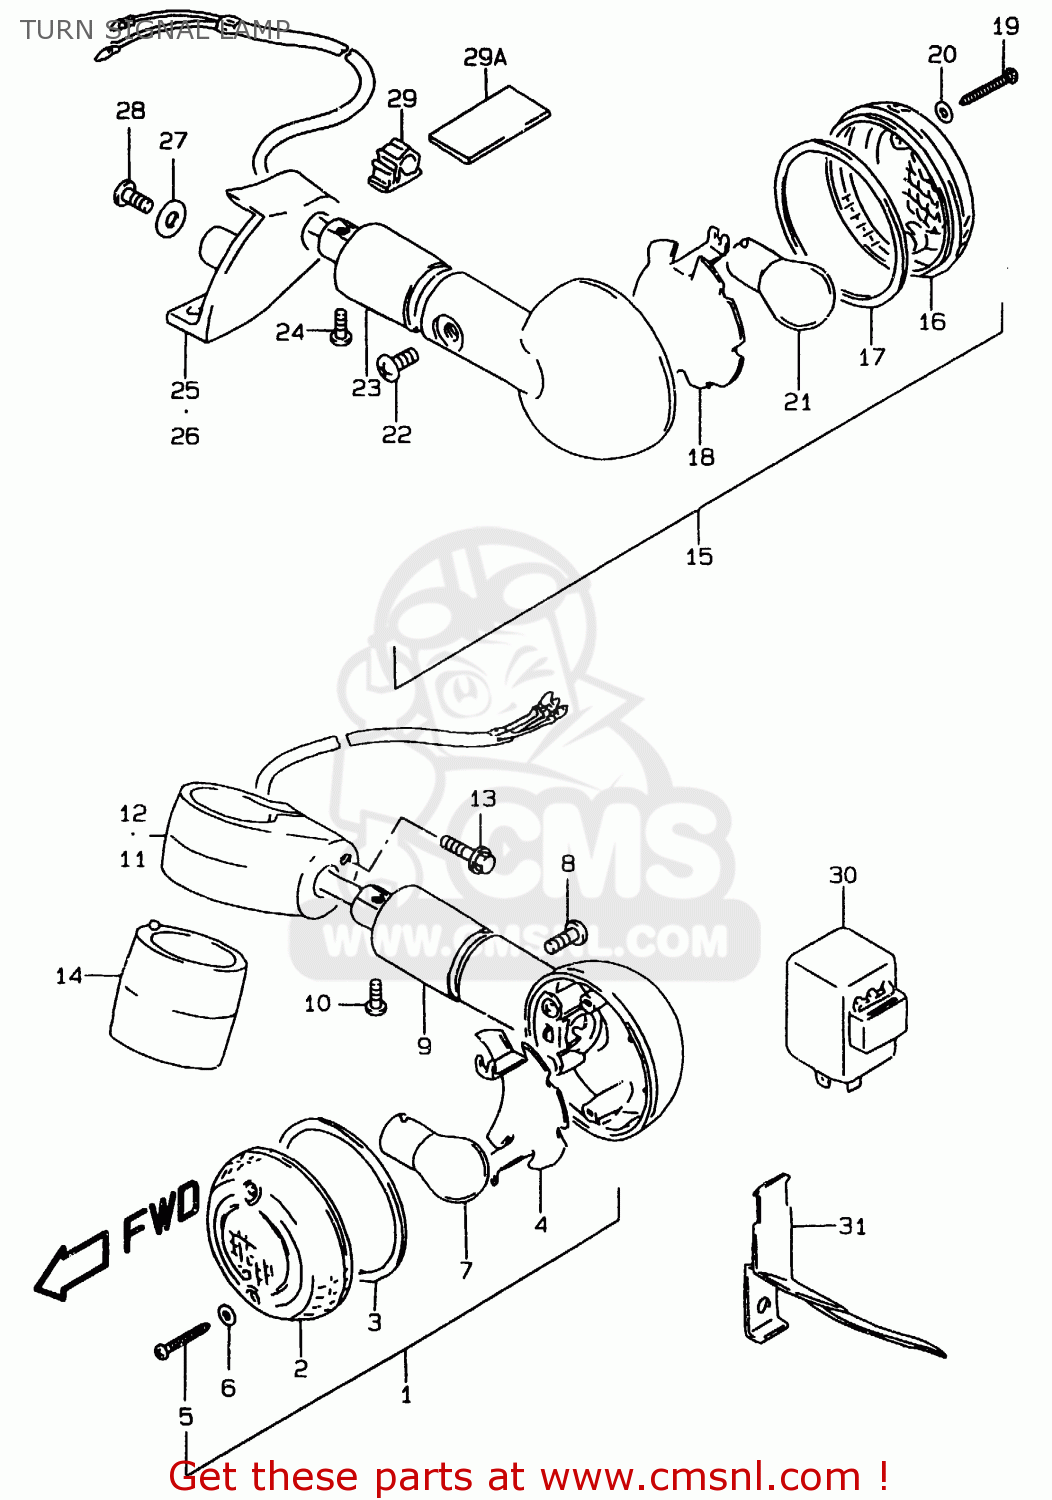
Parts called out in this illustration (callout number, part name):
1	LAMP ASSY,FR TURN SIGNAL
2	LENS
3	GASKET (NAS)
4	REFLECTOR
5	SCREW
6	GASKET (NAS)
7	BULB(12V21W)
8	SCREW
9	STAY,TURNSIGNAL LAMP
10	SCREW
11	BRACKET,FR TURNSIGNAL LAMP,R
12	BRACKET,FR TURNSIGNAL LAMP,L
13	BOLT
14	SPACER,FR TURNSIGNAL LAMP BRKT
15	LAMP ASSY,RR TURNSIGNAL,R
16	LENS
17	GASKET (NAS)
18	REFLECTOR
19	SCREW
20	GASKET (NAS)
21	BULB(12V21W)
22	SCREW
23	STAY,TURNSIGNAL LAMP
24	SCREW
25	BRACKET,RR TURNSIGNAL,R
26	BRACKET,RR TURNSIGNAL,L
27	WASHER(6.5X20X1.6)
28	SCREW 6X12
29	CLAMP
29A	TAPE
30	RELAY ASSY
31	BRACKET,TURNSIGNAL RELAY
